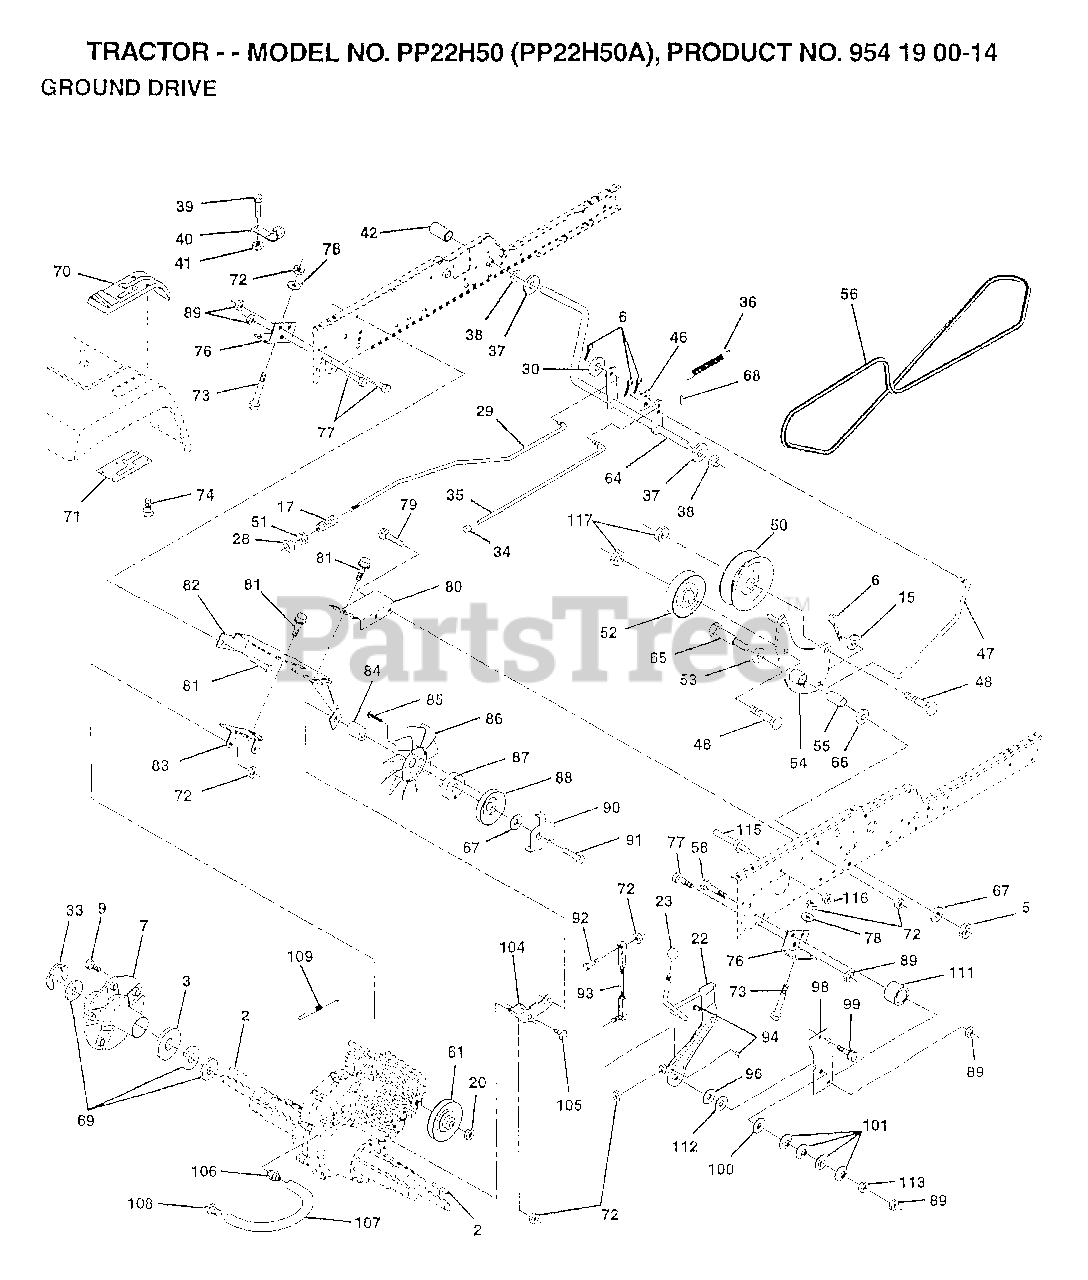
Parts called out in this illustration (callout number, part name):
2	KEY 1/4 X 2.5
3	WASHER T
6	COTTER PIN
7	HUB WHEEL ASM
9	BOLT.HUB.WHL.REAR
15	WASHER
17	SPRING ROD BRAKE
22	ARM ASM SHIFT
23	KNOB.DUCKHEAD.1/2
28	NUT
29	ROD BRAKE
30	WASHER HYT
33	E RING HYT
34	PLUNGER CAP T
35	ROD BRAKE PART GT
36	SPRING.GRND.DRIVE
37	WASHER
38	BUSHING.NYLINER
39	SCREW
40	ACT-SWITCH T
42	"COVER,PEDAL"
46	RETAINER.SPRING
47	ROD.CLUTCH
48	BOLT.3/8-16X1.50
50	FLAT IDLER PULLEY
52	PULLEY.IDLER.V.GR
53	WASHER T
54	ARM ASM CLUTCH
55	"LY, BEARING"
56	BELT-V 84.5
58	BOLT
61	PULLEY TRANSAXLE
64	SHAFT-BRAKE/CLUTC
65	AXLE BOLT
66	WASHER.HARD.BLADE
67	WASHER
68	ROLL PIN STD
69	WASHER
71	"PLATE CONSOLE,SFT"
72	NUT
73	BOLT FIN HEX 5/16
74	SCREW HEXWSH H-L
76	BRACKET TRAN VGTH
77	BOLT
78	WASHER
79	BOLT
80	BRACKET TORQUE RH
81	SCREW
82	BRACKET.MTG.FAN
83	STRAP TORQUE MID
84	SPACER
85	SCREW YTV
86	"FAN 7"" HYDRO"
87	ADAPTER FAN
89	NUT GTV
90	KEEPER BELT
91	SCREW.HXWSH.3/8
93	LINK ASM SHIFT
94	XMAS TREE FASTNER
96	WASHER NICKEL PLT
98	BRACKET SHIFT
99	SCREW LT
100	WASHER COMPRESSIN
101	WASHER-BELLVILLE
104	BRACKET IDLER
105	SCREW CRT
106	O-RING.ASM.70110
107	"LINE FUEL,HYD 15"""
108	CAP.VENT.70109
109	SPRING BRAKE
111	"SPACER-LEVER,SHIF"
112	"WASHER-NYLON,HIGH"
113	NUT
115	"KEEPER,DRIVE BELT"
116	"NUT HEX,LOCK,FLAN"
